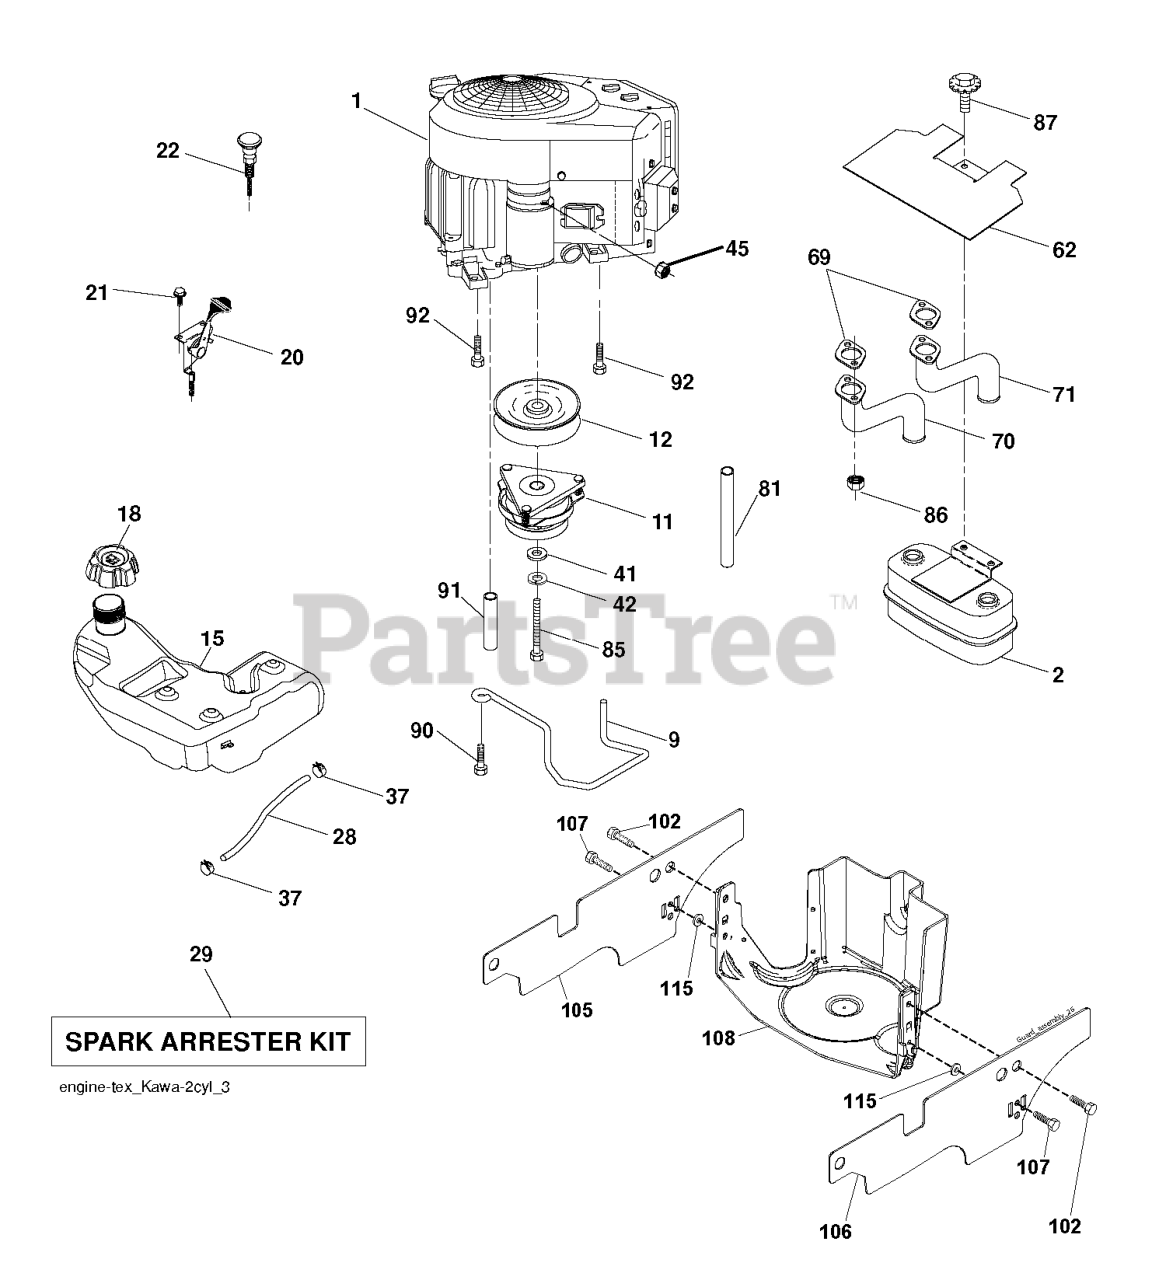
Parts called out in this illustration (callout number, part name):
2	MUFFLER.TWIN.CYL.LOW.TONE
9	KEEPER.BELT.ENGINE.4.2
11	RB.CLUTCH.OGURA.4.4.PD
12	PULLEY.ENGINE.TUFFTORQ
15	TANK.FUEL.4GAL
18	CAP.FUEL.TANK.3"GREY
20	THROTTLE CABLE
21	SCREW.#10 X 0.750.BOS
22	CONTROL.CHOKE.ERGO.PUSH-IN.BLA
28	REPL BY 532 00 85-43
29	KIT.SPARK ARRESTOR 794945 B&S
37	HOSE CLAMP
42	LOCKWASHER
45	NUT
62	RP SHIELD HEAT MUFFLER
70	EXHAUST TUBE LH KAWI
71	EXHAUST TUBE RH KAWI
81	TUBE, DRAIN OIL ASM.
85	BOLT HEX 7/16-20X4-1/4"
86	NUT.HEX.FLANGE.TOPLOCK
87	BOLT.5/16-18UNCX1.W/SEMS.BLK
90	SCREW 3/8-16X1
91	BUSHING.1.375OD
92	SCREW 3/8-16X1
102	SCREW
105	SHIELD.SIDE.LH.3842"TEX FRENCH
106	SHIELD.SIDE.RH.3842"TEX FRENCH
107	SCREW.1/4-20X5/8
108	ENGINE COVER
115	PALNUT 1/4
